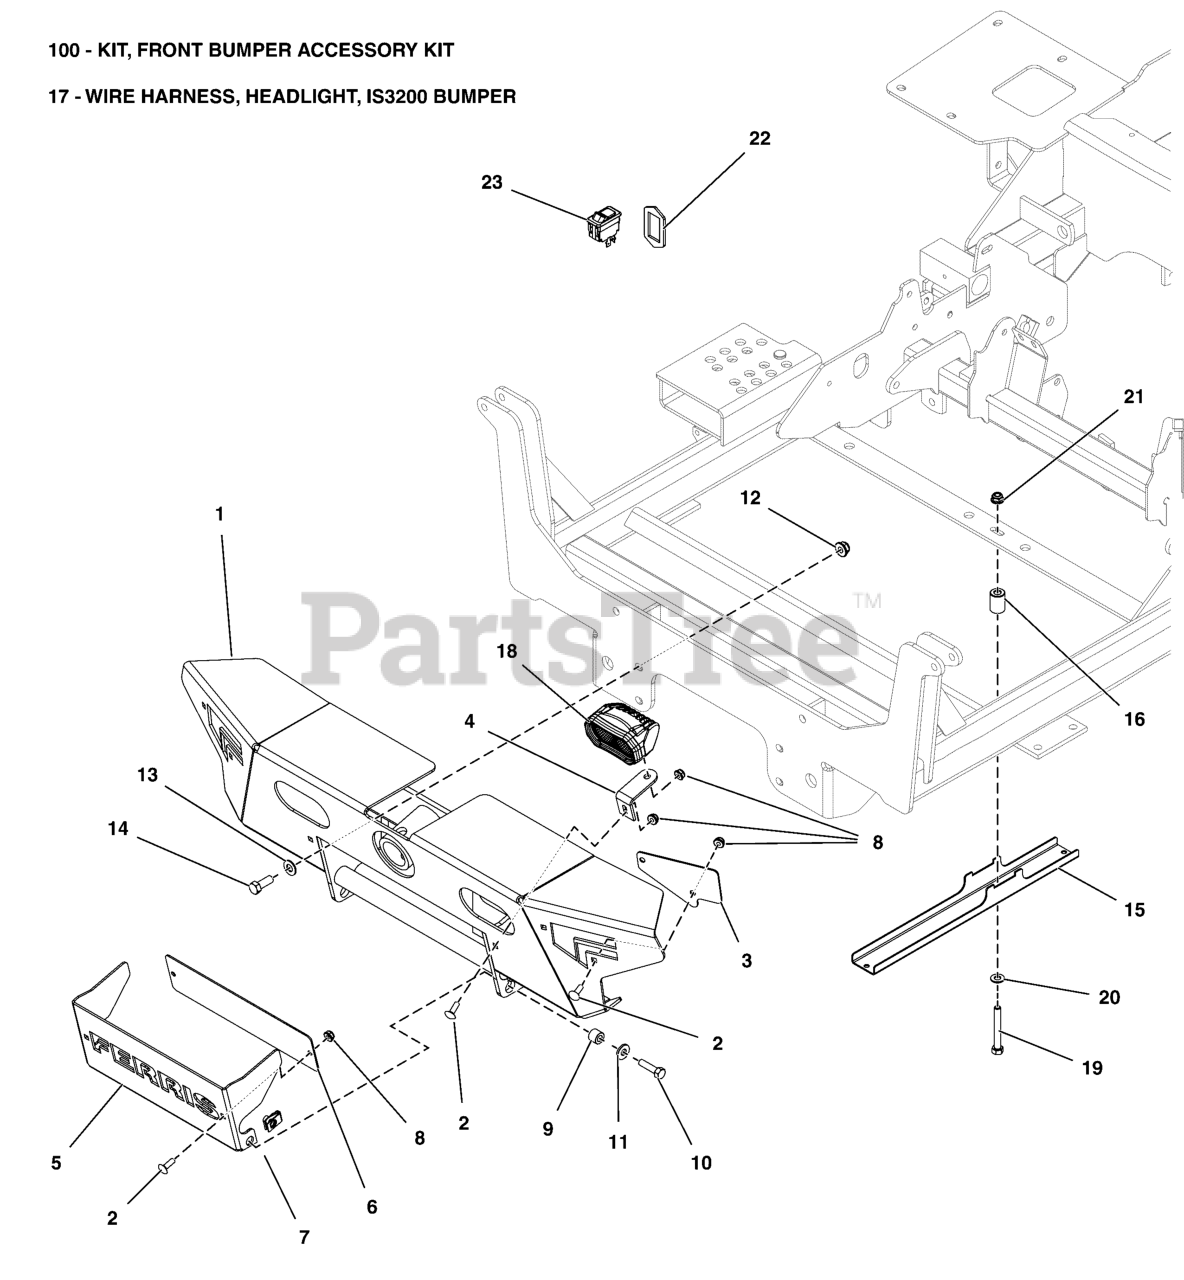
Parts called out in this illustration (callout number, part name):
1	WELD, FRONT BUMPER, 3200 MDNT - BLK
2	BOLT CARRIAGE 1/4-20X3/4 GR 5 ZNCOAT BLK
3	PLATE, BACKSPLASH, 3200 MDNT - RED
4	PLATE, LIGHT TAB, 3200 MDNT - BLK
5	PLATE, COVER, 3200 MDNT - BLK
6	PLATE, BACKSPLASH COVER, 3200 MDNT - RED
7	BODY CLIP, 5/16-18-7GA MATERIAL
8	NUT, 1/4-20 Hex Nylock Flange
9	SPACER, .33 X .63 X .50, CZ
10	BOLT, 5/16-18 X 1-1/4 GD5 TFL, CZ
11	WASHER, 5/16 GRADE 9, FLAT
12	NUT, 3/8 - 16 HEX NYLOCK FLANGE
13	WASHER, 3/8 SAE
14	BOLT, 3/8-16 X 1" GD5 CZ
15	PLATE, WIRE CHANNEL, 3200 BUMPER
16	SPACER .32 X .75 X 1.06
17	WIREHARNESS, HEADLIGHT, IS3200 BUMPER
18	HEADLIGHT, 5104888 W/ SHRINK TUBE
19	BOLT, 5/16-18 X 2-1/2" GD5 YZ
20	WASHER, 5/16" SAE
21	NUT, 5/16-18 HEX NYLOCK FLANGE NUT
22	RING, SWITCH RETAINER
23	SWITCH, HEADLIGHT
100	KIT, FRONT BUMPER ACCESSORY, IS3200Z
